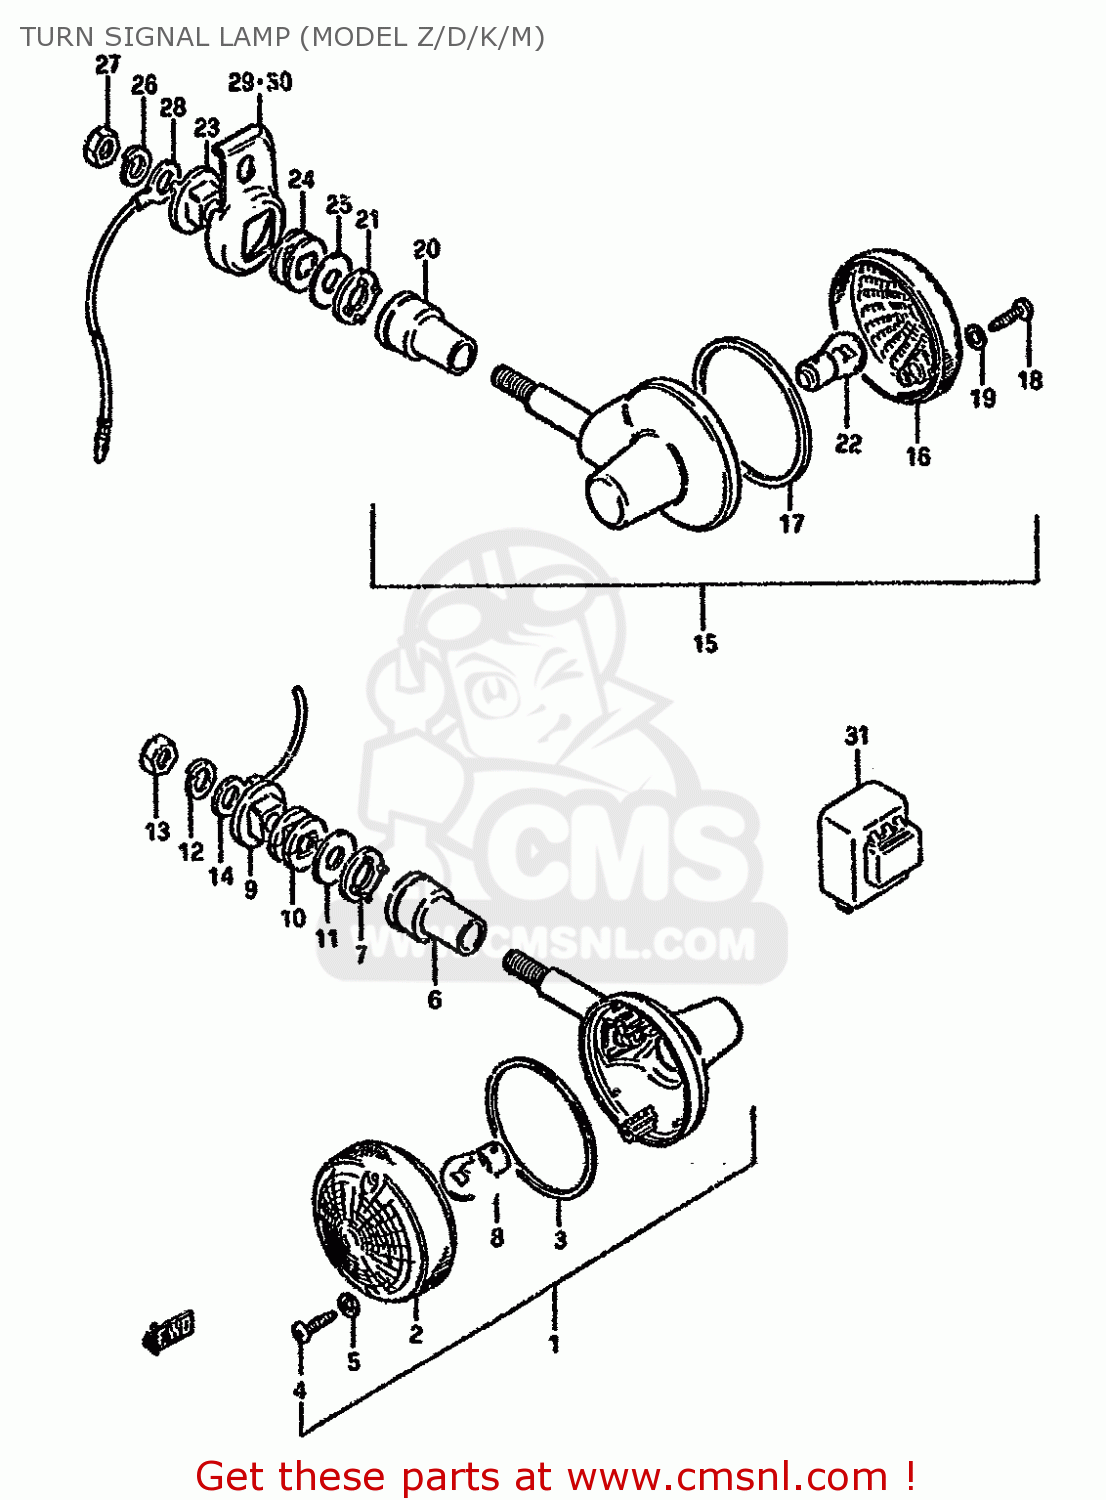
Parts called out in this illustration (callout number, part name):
1	LAMP ASSY, REAR TURN SIGNAL
2	LENS
3	GASKET (NAS)
4	SCREW
5	GASKET (NAS)
6	COVER,STAY
7	SPACER
8	BULB(12V23W,STANLEY,A4577A)
9	SPACER
10	CUSHION
11	WASHER (10.5X30X2.3)
12	LOCK WASHER
13	NUT
14	LEAD WIRE,EARTH
15	LAMP ASSY, REAR TURN SIGNAL
16	LENS
17	GASKET (NAS)
18	SCREW
19	GASKET (NAS)
20	COVER,STAY
21	SPACER
22	BULB(12V23W,STANLEY,A4577A)
23	SPACER
24	CUSHION
25	WASHER (10.5X30X2.3)
26	LOCK WASHER
27	NUT
28	LEAD WIRE,EARTH
29	BRACKET,RR TURNSIGNAL LAMP,R
30	BRACKET,RR TURNSIGNAL LAMP,L
31	RELAY ASSEMBLY,TURN SIGNAL
